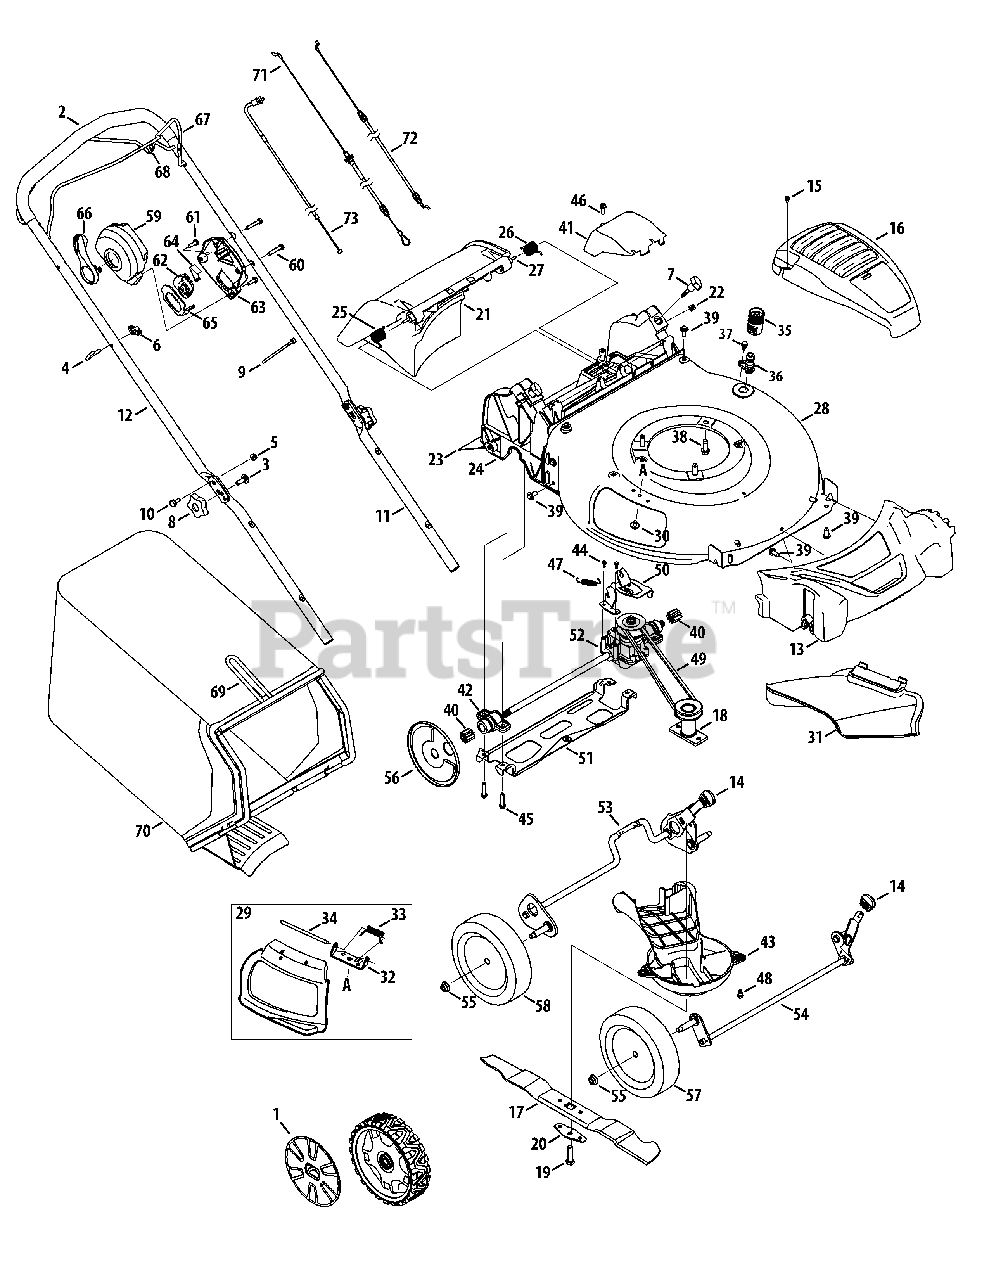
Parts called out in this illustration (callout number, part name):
3	Carriage Screw ,5/16-18
4	Rope Guide
5	Nut, Flange Lock, 1/4-20
7	Wing Nut
9	Cable Tie
10	Shdr. Screw, .375 x .126 x 1/4-20
11	Lower Handle
13	Front Cover
14	Adjustment Knob
15	Screw, HL, #12-16 x 1.00
16	Engine Shroud
17	Mulching Blade
18	Blade Adapter
19	Screw, 3/8-24 x 1.50
20	Blade Bell Support
21	Rear Discharge Door Assembly
22	Nut, Sq., 1/4-20
23	Trail Shield
24	Rear Baffle
25	Torsion Spring - RH
26	Torsion Spring - LH
29	Mulch Plug (Incl. 32-34)
31	Side Discharge Chute
32	Chute Deflector Bracket
33	Torsion Spring
35	Water Nozzle Adapter
36	Water Nozzle
37	Screw, Shldr., 1/4-20 x .50
38	Screw, tt, 3/8-16 x 1.00
39	Screw, 5/16-14 x .750
40	Spur Gear, 10T
41	Transmission Cover
42	Bearing Assembly
43	Engine Baffle
44	Screw, Hex Washer, .159 x .43
45	Screw, 1/4-15 x 1.25
46	Screw, 1/4-15 x .750
47	Exten. Spring, 2.675
48	Screw, Shldr., 1/4-20 x .50
50	Transmission Bracket
51	Rear Support Bracket
52	Transmission
53	Rear Axle Assembly
54	Front Axle Assembly
55	Flange Lock Nut, 3/8-16
56	Wheel Dust Cover
57	Front Wheel, 8 x2
58	Rear Wheel, 8 x 2
59	Control Housing Assembly
60	Screw, 1/4-15 x 1.50
61	Screw, 1/4-15 x .750
62	Speed Cable Actuater
63	Lower Control Housing
64	Shift Lever Spring
65	Cable Adjustment Plate
66	Speed Select Lever
67	Blade Control
68	Drive Control
69	Grass Catcher Frame
71	Speed Adjustment Cable
72	Control Cable
73	Speed Select Cable
